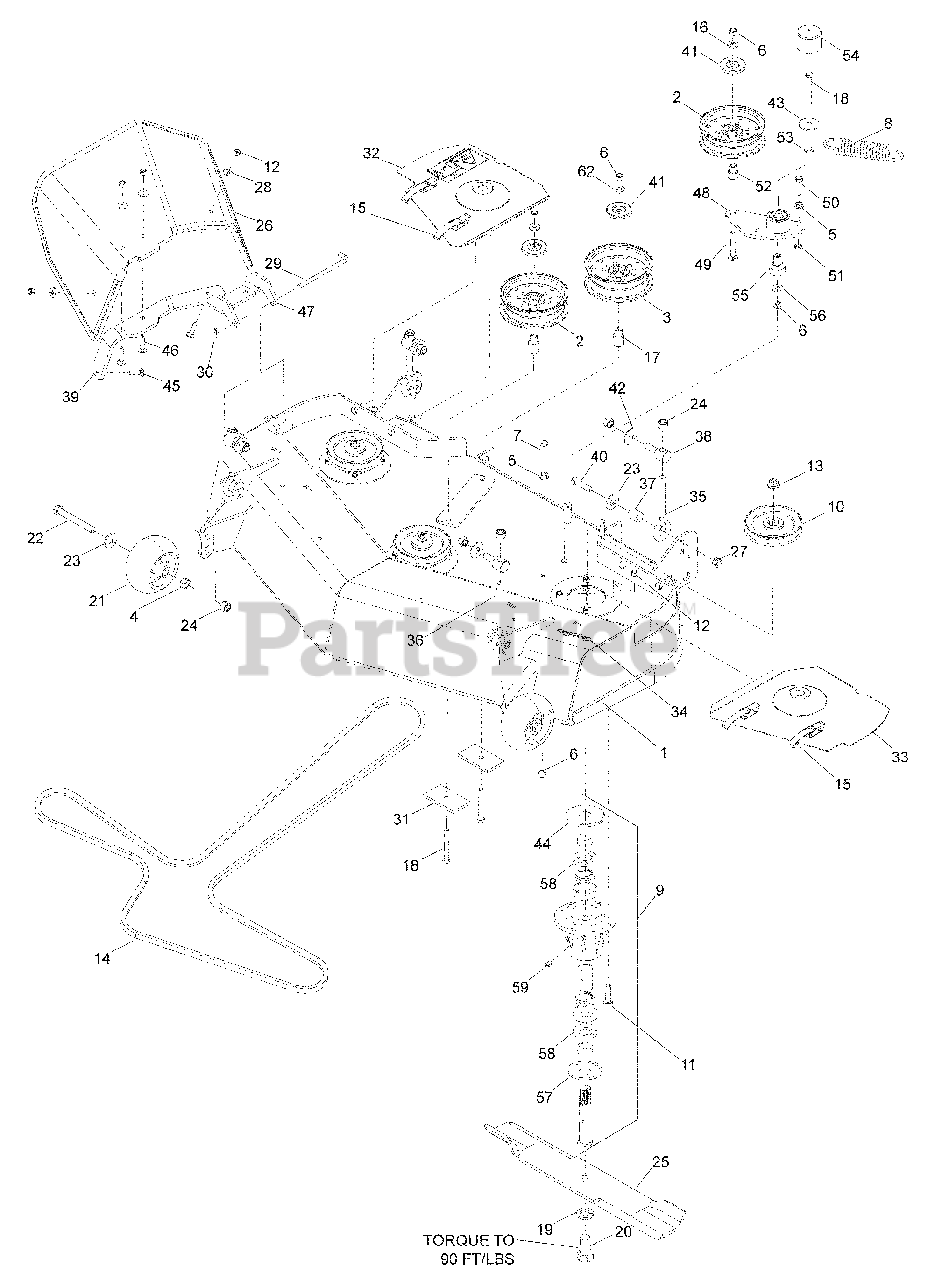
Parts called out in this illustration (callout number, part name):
1	DECK w/DECALS
2	PULLEY, IDLER
3	PULLEY, IDLER
5	NUT 3/8-16 WHIZLK
6	NUT 3/8-16 HEX NYLOC
7	HCS 3/8-16 x 1¼
8	SPRING, EXTENSION
9	SPINDLE ASSEMBLY
11	HCS 5/16-18 x 1¼
12	NUT 5/16-18 HEX NYLOC
13	NUT ¾-16 FLANGE
14	BELT, DECK
15	DRAW LATCH
16	WASHER 3/8 THICK
17	BUSHING, IDLER
18	HCS 3/8-16 x 3
19	WASHER 5/8 SPLIT LOCK
20	HCS 5/8-18 x 1¼
21	WHEEL, GAUGE
22	HCS ½-13 x 4
23	WASHER ½ SPRING
24	NUT ½-13 HEX NYLOC
25	BLADE 145/8
26	CHUTE, DISCHARGE
27	NUT 7/16-14 HEX CTRLK GR A
28	WASHER 5/16 STD FLT
29	PIN, CLEVIS
30	PIN, COTTER 1/8 x ¾
31	PAD
32	BELT SHIELD ASSM RT
33	BELT SHIELD ASSM LT
34	DECAL, TUNNEL
36	EYE BOLT ½-13
39	REINFORCEMENT, BRKT
40	HCS 7/16-14 x 1¾
41	SHIELD, DUST
43	WASHER 3/8 SPECIAL
44	DUST CAP, TOP
45	RHSNB 5/16-18 x 1¼
46	RHSNB 5/16-18 x 1½
47	BRACKET, CHUTE
48	ARM, IDLER w/BEARINGS
49	RHSNB 3/8-16 x 2¾
50	HCS 3/8-16 x 1½ GR8
51	NUT 3/8-16 HEX JAM
52	BUSHING, IDLER
53	WASHER 3/8 SAE FLT
54	CAP, VINYL
55	BEARING, PIVOT
56	WASHER 3/8 FLAT STD
57	DUST CAP, BOTTOM
58	SEAL, SHAFT
59	GREASE POPPET
